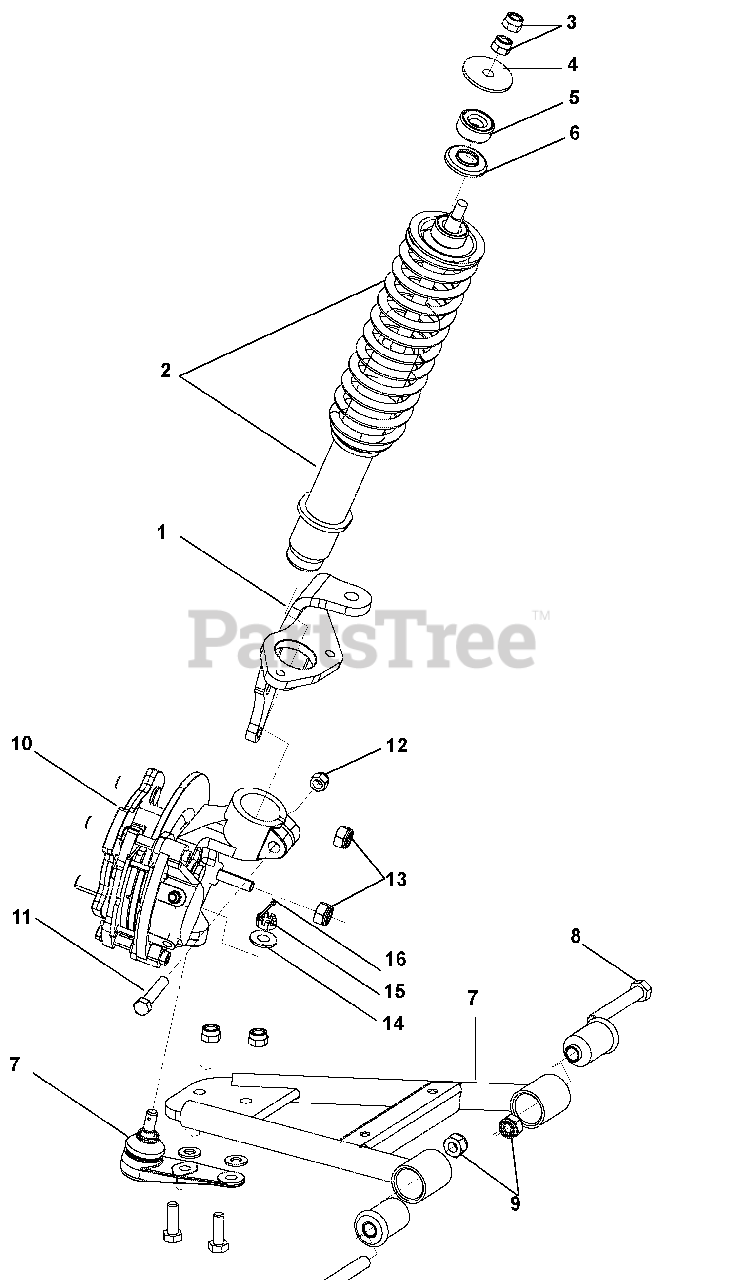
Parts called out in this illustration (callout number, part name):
1	STEERING BRACKET RIGHT
2	STRUT/COIL SPRING ASM
3	NUT HEX JAM M10 X 1.25 6MTHK YLW
4	WASHER, FLAT
5	GROMMET, RUBBER MOUNT
6	WASHER, STRUT MOUNT
7	CONTROL ARM ASM, LH
8	HHCS M12 X 1.75 X 80 PLT
9	NUT NEX NYLOCK M12 X 1.75 PLT
10	RH DISK BRAKE ASM 172MM W/ JNT
11	HHCS 3/8-16 X 2 GR8 PLT
12	NUT LOCK 3/8-16 NYLON INSERT
13	NUT HEX NYLOCK M10 X 1.5 PLT
14	WASHER FLAT 3/8 USS PLT
15	NUT HEX SLOTTED M10 X 1.25 PLT
16	PIN COTTER 3/32 X 1 LONG
